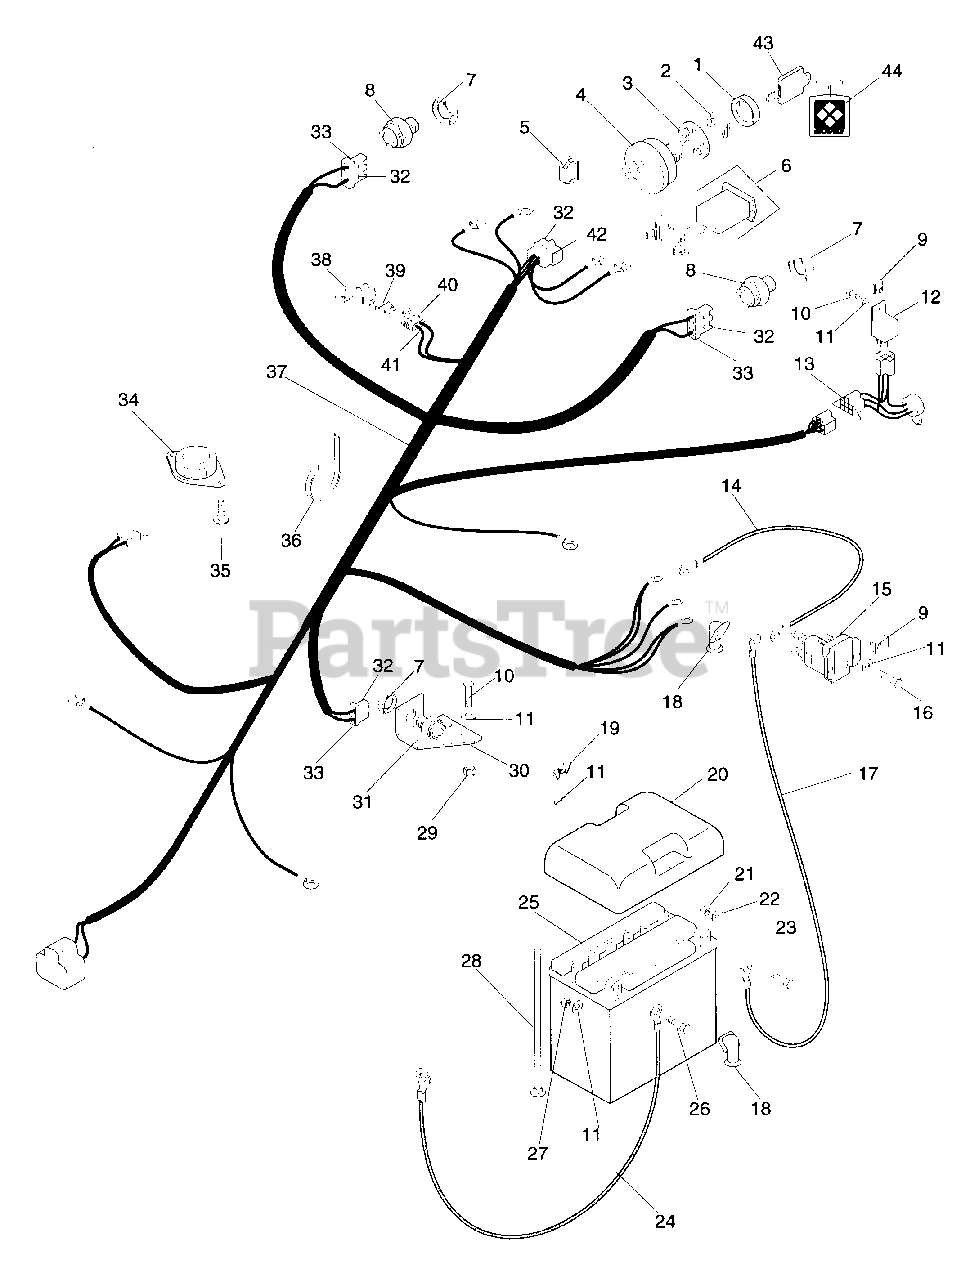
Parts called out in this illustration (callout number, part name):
1	Cap - Ignition Switch
2	Nut - Panel .562 - 24 Greco
3	Wshr - Lock Int .563 x .040 Pl
4	Ignition Switch
4	Switch, Ignition w/Ground
5	Light, Indicator
6	Hour Meter
7	Nut, Stamped 9/16 - 18
8	Switch - Neutral Start N.O.
9	Nut Speed .25 - 20
10	Blt - Hex .25 - 20 x .63
11	Wshr - Fl - Stl .281 x .62 x .065 Pl
12	Relay
13	Module, Time Delay
14	Cbl, Slnd To Starter
14	Cable, Starter
15	Solenoid
16	Blt - Hex .25 - 20 x .63
17	Cbl, Battery To Solenoid
18	G Boot, Insulator
19	Nut - Wing .250 - 20
20	Cvr, Battery
21	Nut - Lk - Nyl .312 - 18 Pl
22	Wshr - Fl - Stl .344 x .688 x .065 Pl
23	Blt - Hex .31 - 18 x 1.00 Pl Gr 5
24	Cbl, Negative Battery
25	12 Volt Battery
26	Blt - Hex.25-20 x.75 Pl Gr 5
27	Nut - Lk - Nyl .250 - 20 Pl
28	Blt - Rdhdsqnk .25 - 20 x 7.00
29	Nut - Lk - Nyl .250 - 20 91
30	Brkt, Interlock Switch
31	Switch
32	Terminal
33	Conn, 2-Wire Switch
34	Switch - Seat
35	Scr - Mch .25 - 20 x .50
36	Tie Wrap, Black
37	Hrns, Wiring 18 HP Kohler
37	Harness, Wiring 16 B & S PM100
38	Cvr
39	Fuse, 25 AMP
40	Asm, Conn Weather Tight
41	Term., For 10-12 Ga Wire
42	Connector
43	Ignition Switch Key
44	Key Chain
